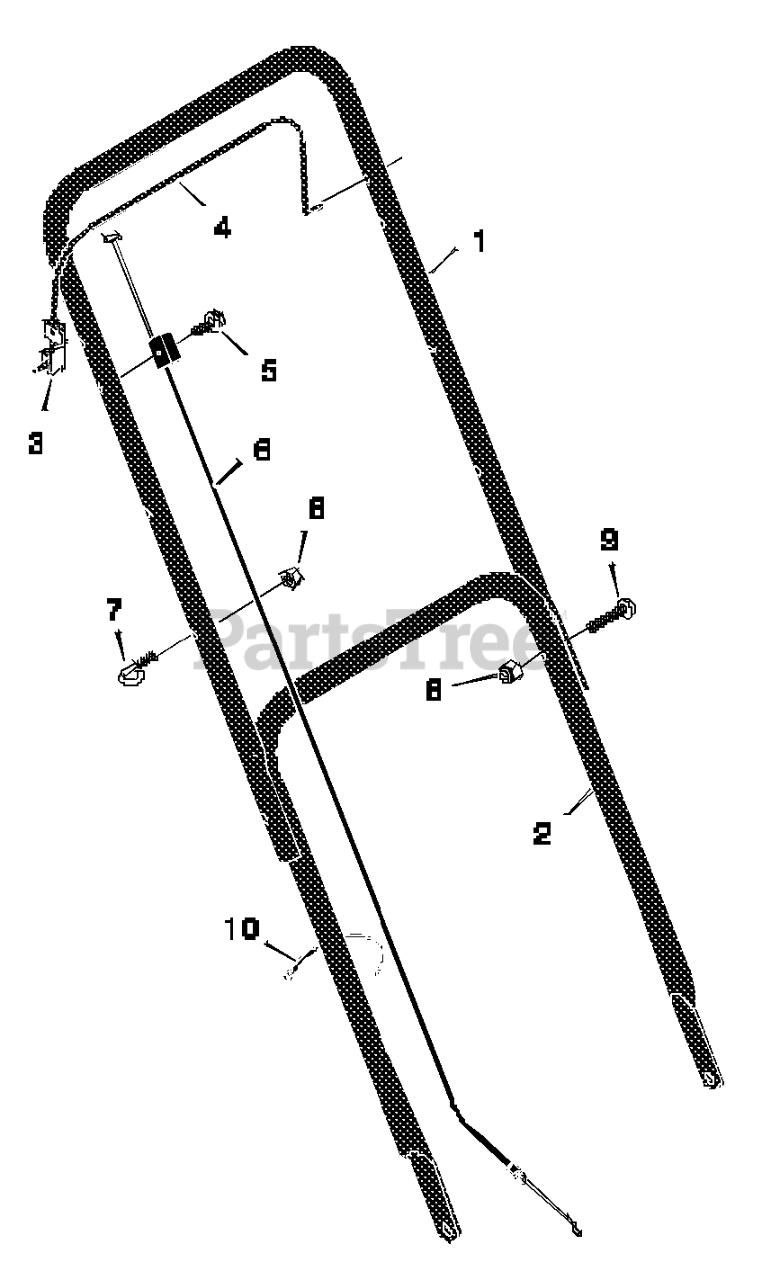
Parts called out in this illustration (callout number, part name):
1	Handle, Upper (Black)
2	Handle, Lower (Black)
3	Bracket, Stop Lever
4	Lever, Stop
6	Engine Stop Cable
7	GUIDE, ROPE
8	Locknut
10	Fastener, Cable
